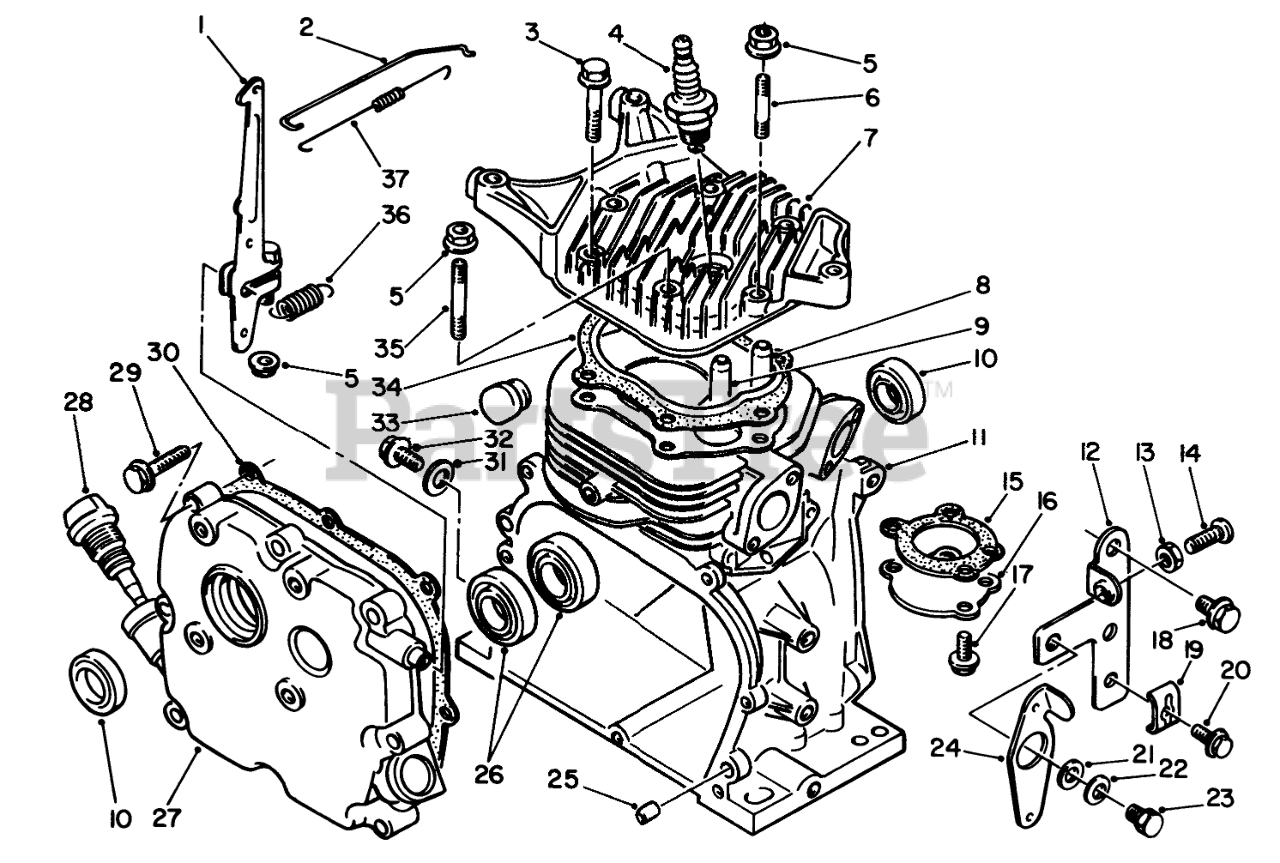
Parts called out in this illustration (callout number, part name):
1	Lever-Throttle Conlrol
2	Rod-Carburetor
4	Spark Plug
6	Bolt-Stud
7	Cylinder Head
8	Guide-Intake Valve
9	Guide-Exhaust Valve
10	OIL SEAL
11	Cylinder Assembly
12	Bracket-Governor Control
13	Nut-Jam
14	Screw-Round Phillips Hd.
15	GASKET
16	Cover-Level Sensor
19	CLAMP-CABLE
21	WASHER
22	Washer
24	Lever
26	Bearing
27	Cover-Crankcase Side
28	Gauge-Oil Level
30	CRANKCASE GASKET
31	Gasket
32	Bolt
34	CYL. GASKET
35	Bolt-Stud
36	SPRING
37	SPRING
